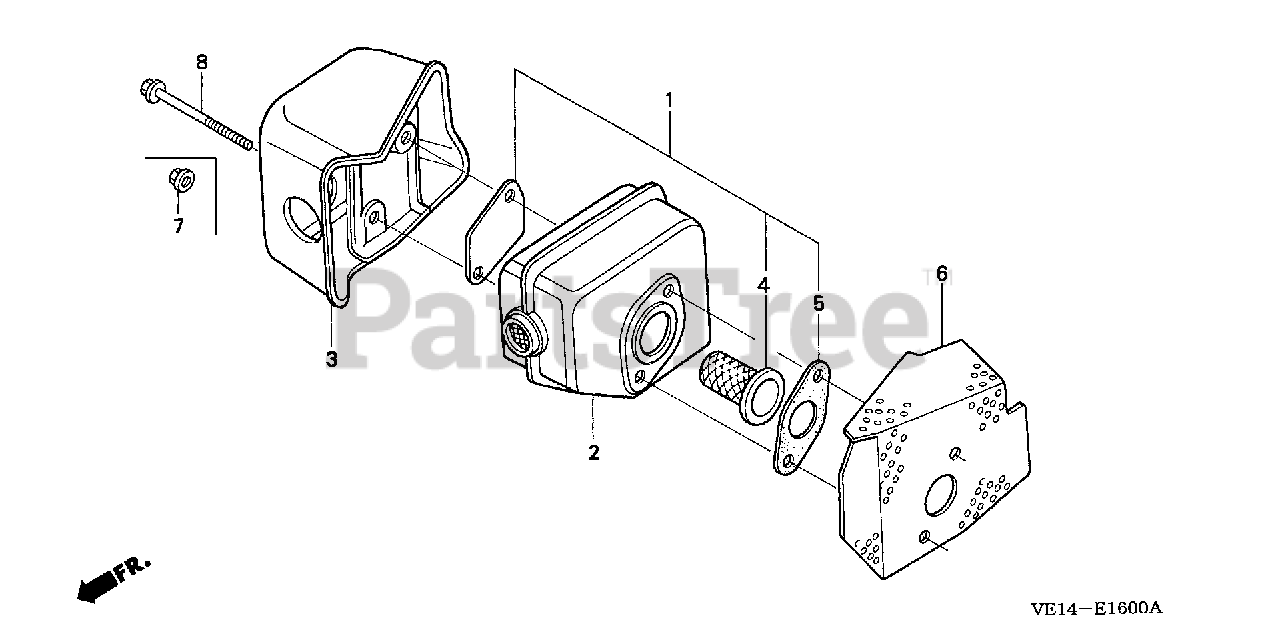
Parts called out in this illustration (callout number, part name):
1	ARRESTER KIT, SPARK
2	MUFFLER
3	PROTECTOR, MUFFLER
4	ARRESTER KIT, SPARK
5	GASKET, MUFFLER
6	GASKET, MUFFLER
7	NUT, SELF-LOCK (6MM)
